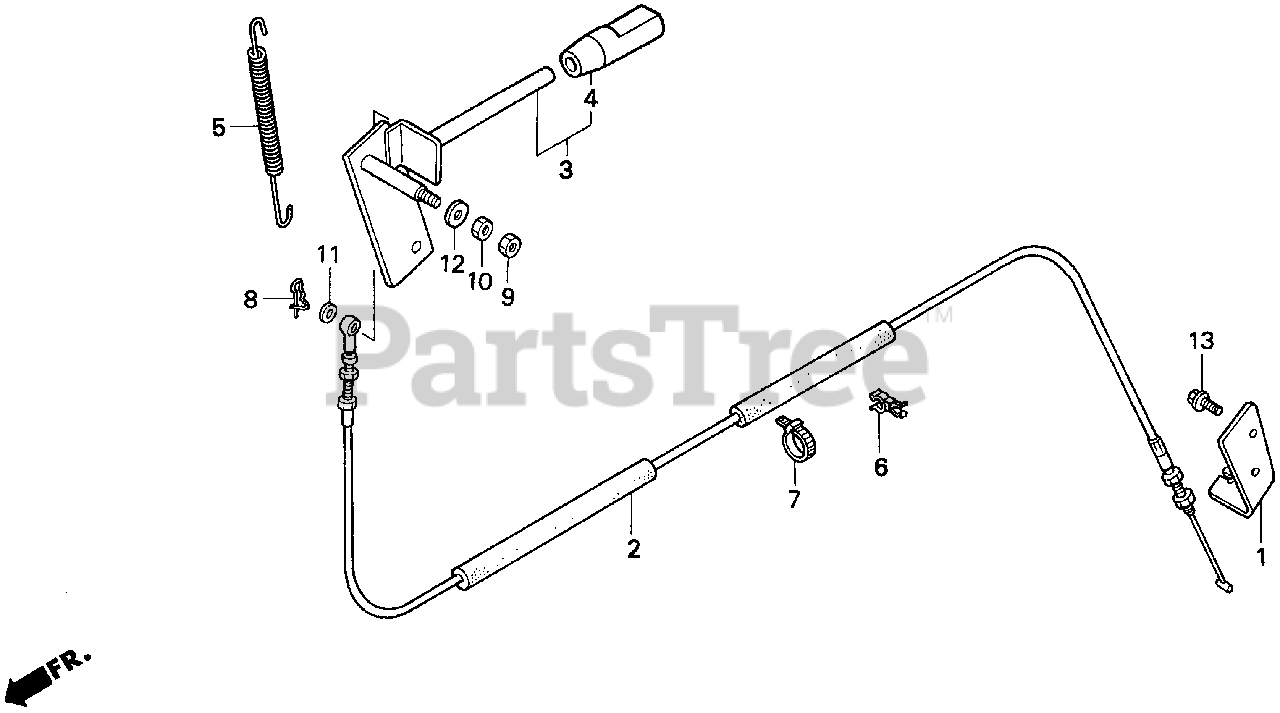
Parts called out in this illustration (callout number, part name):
1	HOLDER, P.T.O. CABLE
2	CABLE, P.T.O. CLUTCH
3	LEVER, P.T.O.
4	KNOB, FR. P.T.O. LEVER
5	SPRING, P.T.O. LEVER
6	CLAMP, RESERVE TANK TUBE
7	BAND, CABLE (120MM) (BLACK)
8	PIN, SNAP (6MM)
9	NUT, HEX. (6MM)
10	NUT, HEX. (6MM)
11	WASHER, PLAIN (6MM)
12	WASHER, PLAIN (6MM)
13	BOLT, FLANGE (6X16)
